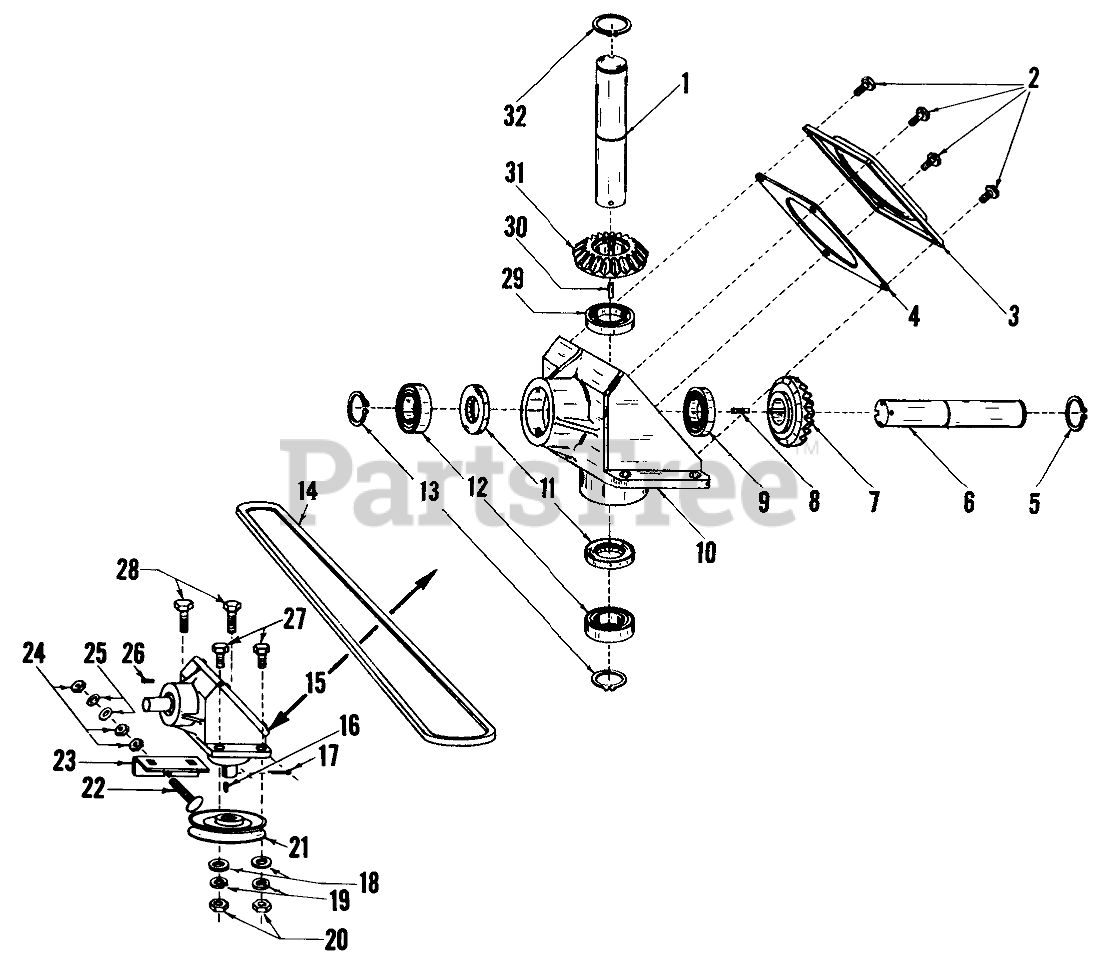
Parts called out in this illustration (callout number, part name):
1	Shaft
2	Self Tapping Screw
3	Cover
4	Gasket Cover
5	Retainer Ring
6	Shaft
9	Bearing
10	Housing
11	Oil Seal
12	Ball Bearing
13	Retainer Ring
15	Gear Box Assembly
17	Cotter Pin
18	Washer
19	Washer
21	Pulley w/Set Screw
22	Carriage Bolt
23	Belt-Adjusting Plate
25	Washer
27	Capscrew
28	Capscrew
29	Bearing
32	Retainer Ring
